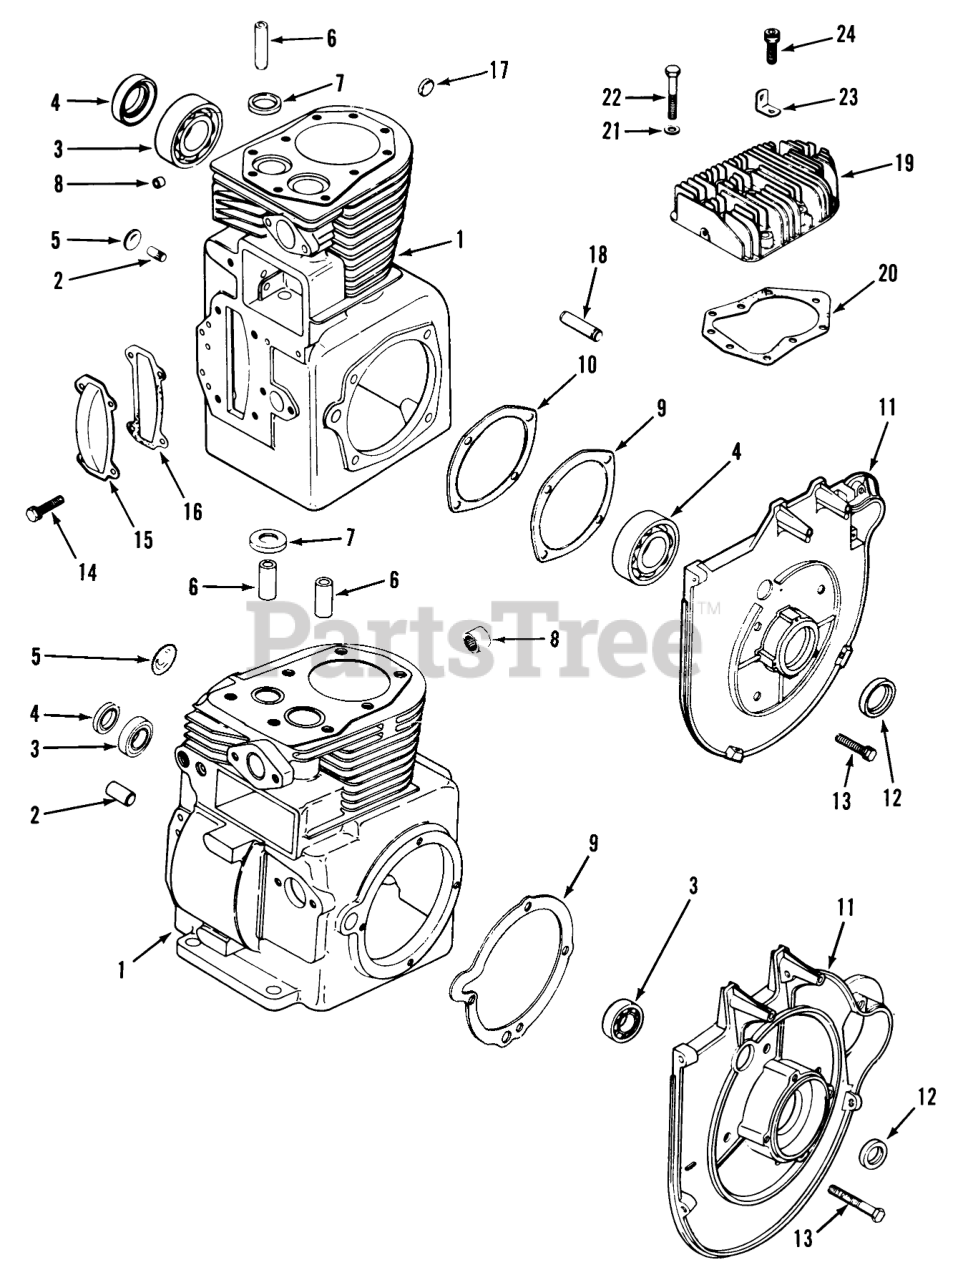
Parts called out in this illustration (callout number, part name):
1	Cylinder Block-Service With Short Block (Includes Crankshaft)
2	Governor Gear Shaft 308 Only
3	Ball Bearing 308 Only
4	Rear Oil Seal 308 Only
6	Guide-Valve
7	Exhaust Valve Insert
8	Bearing
9	Bearing Plate Gasket 308 Only
10	Gasket
11	Bearing Plate 308 Only
12	Front Oil Seal 308 Only
13	H.C. Sems Screw 1/4-20 x 3/4 308
14	Screw
15	Cover
16	Gasket
17	Plug 5/16 O.D. 310
18	Shaft-Balance Gear
19	Cylinder Head 308 Only
20	Head Gasket 308 Only
21	Plain Washer 5/16 308 Only
22	Hex Hd. Screw 5/16-18 x 1/2 308
23	Lifting Strap
24	Screw
